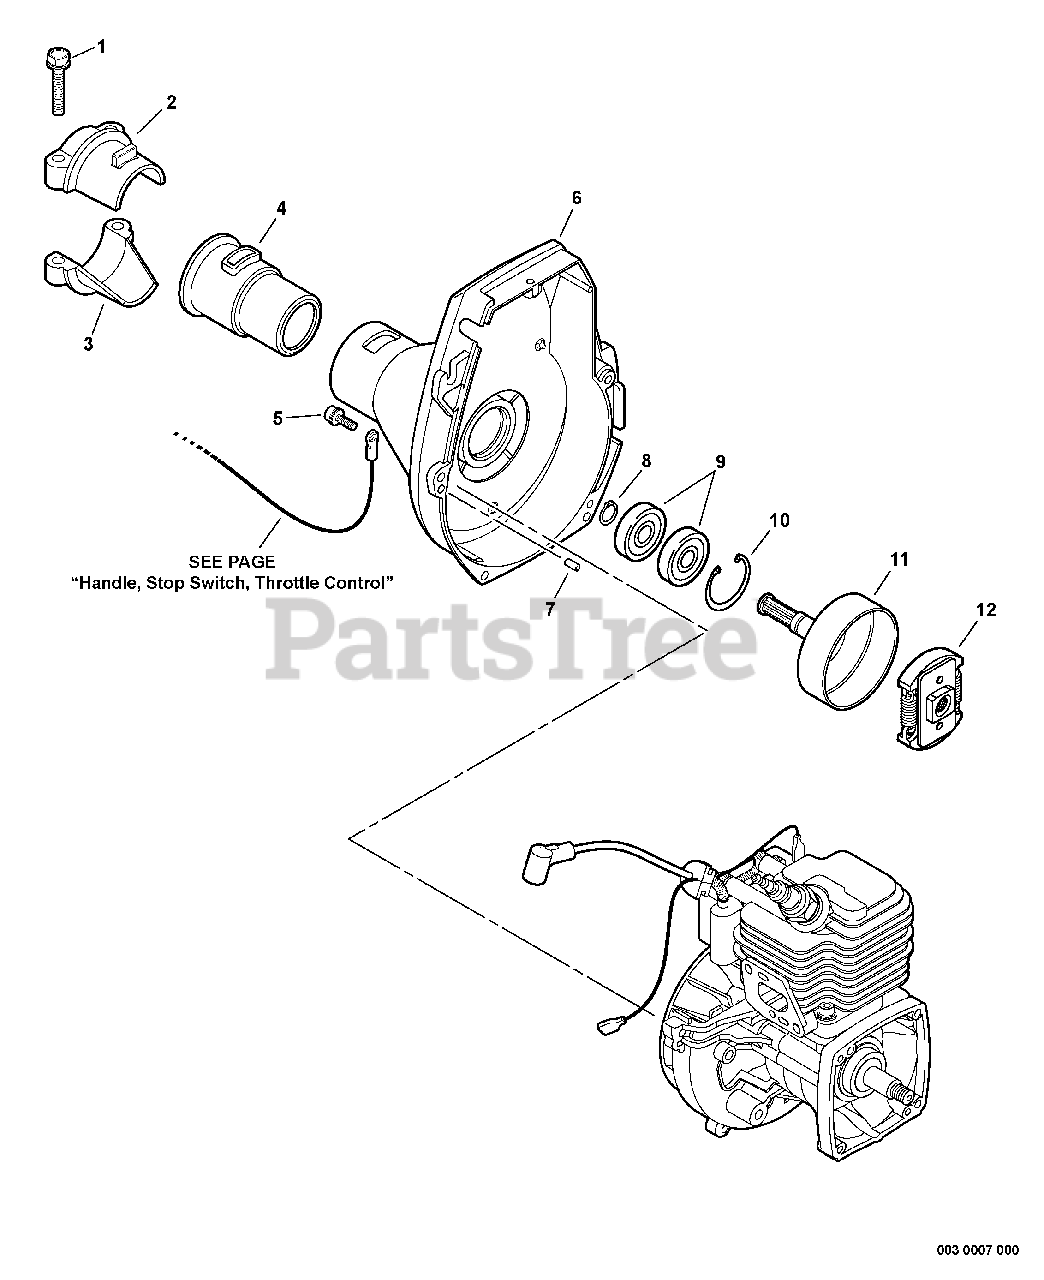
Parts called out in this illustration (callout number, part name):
1	BOLT - 5×25
2	HOLDER, MAIN PIPE - UPPER
3	HOLDER - LOWER
4	CUSHION Ø25
5	BOLT 4×16
6	COVER ASSY, FAN
7	PIN, LOCATING 4
8	RING, RETAINING - 12
9	BEARING, BALL 6001
10	RING, SNAP 28
11	DRUM, CLUTCH
12	CLUTCH ASSY
